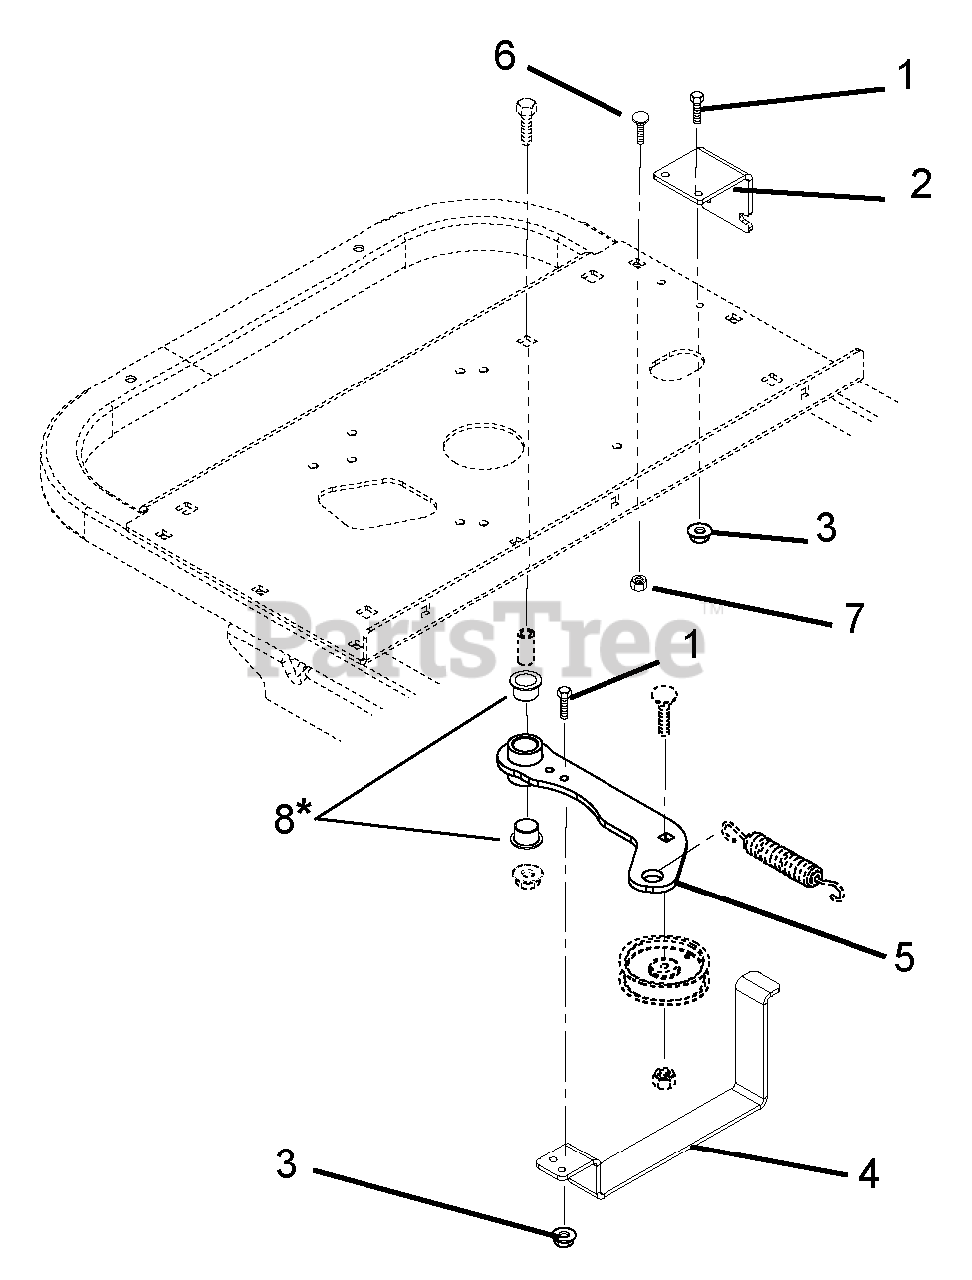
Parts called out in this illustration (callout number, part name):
1	1/4" x 3/4" Hex Bolt
2	Cold Start Latch
3	1/4" Top Lock Flange Nut
4	Cold Start Handle
5	Idler Weldment
6	3/8" x 2" Round Head Square Neck Bolt
7	3/8" Center Jam Nut
8	3/4" x 7/8" x 5/8" x 1-1/8" Flange Bushing
